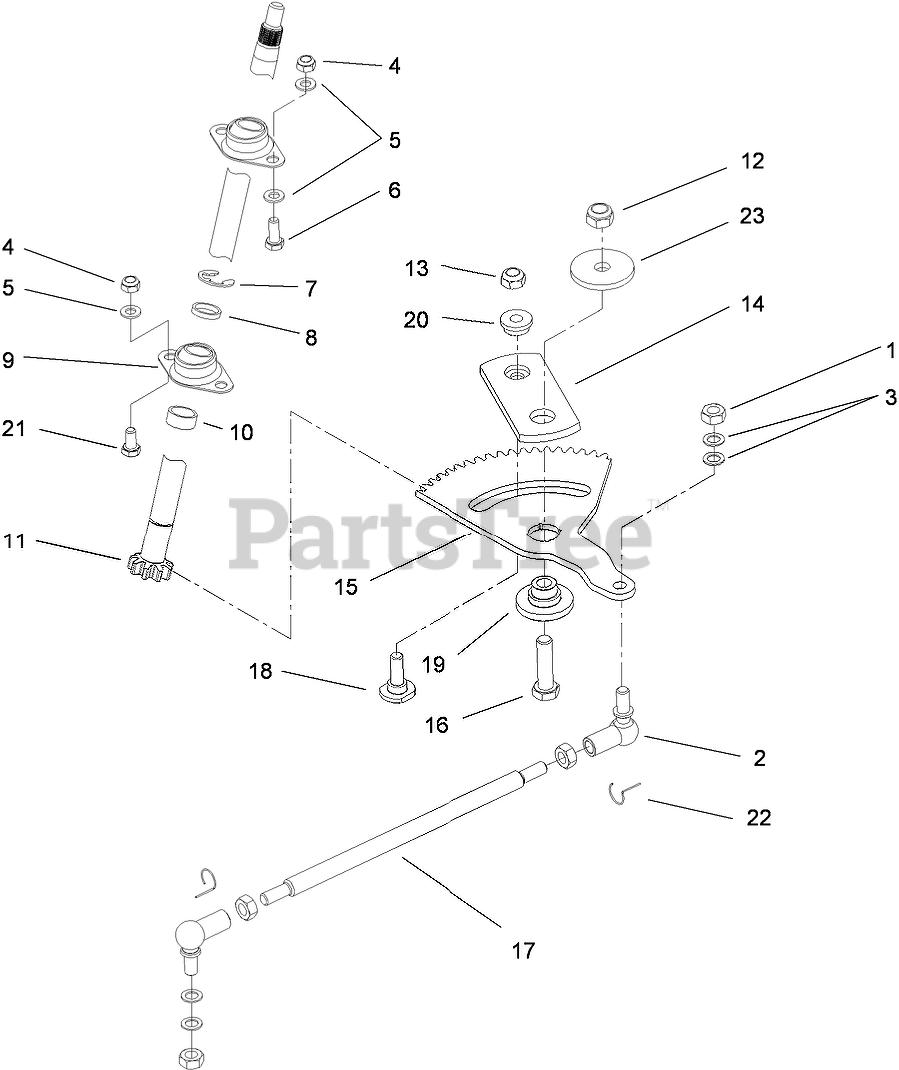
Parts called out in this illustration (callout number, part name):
1	NUT-LOCK, NI
2	JOINT-BALL, ANGLE
3	Washer
4	NUT-LOCK, NI
5	WASHER-PLAIN
6	SCREW-HH
7	CLIP-SPRING
8	SPACER-UPPER
9	BEARING-SPHERICAL
10	SPACER-LOWER
11	Shaft-Steering
12	NUT-LOCK
13	NUT-LOCK, NI
14	Plate-Steering
15	GEAR-SECTOR
16	SCREW-HH
17	LINK-DRAG
18	Bolt-Shoulder
19	Pivot-Steering
20	Bushing
21	SCREW-HH
22	Stirrups-Locking
23	WASHER
